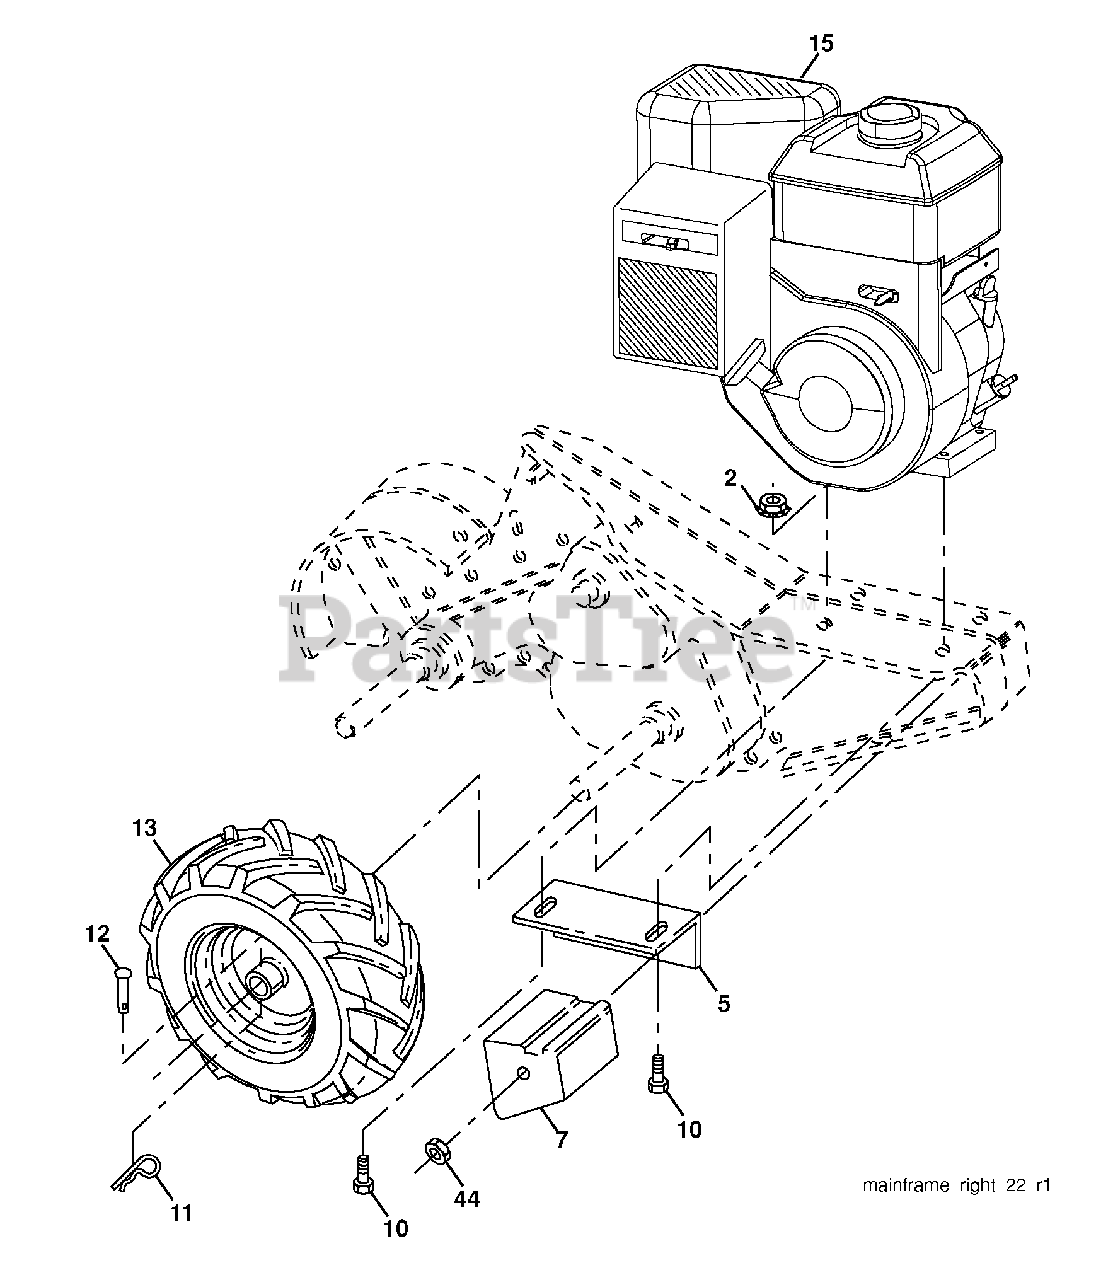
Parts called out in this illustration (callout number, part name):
2	Locknut, Hex, Flange 5/16-18
5	Bracket, Reinforcement RH
7	Counter Weight
10	Bolt, Hex 5/16-18 x 1-1/2
11	Clip, Hairpin
12	Rivet, Drilled
44	Nut, Keps Hex 3/8-16 unc
